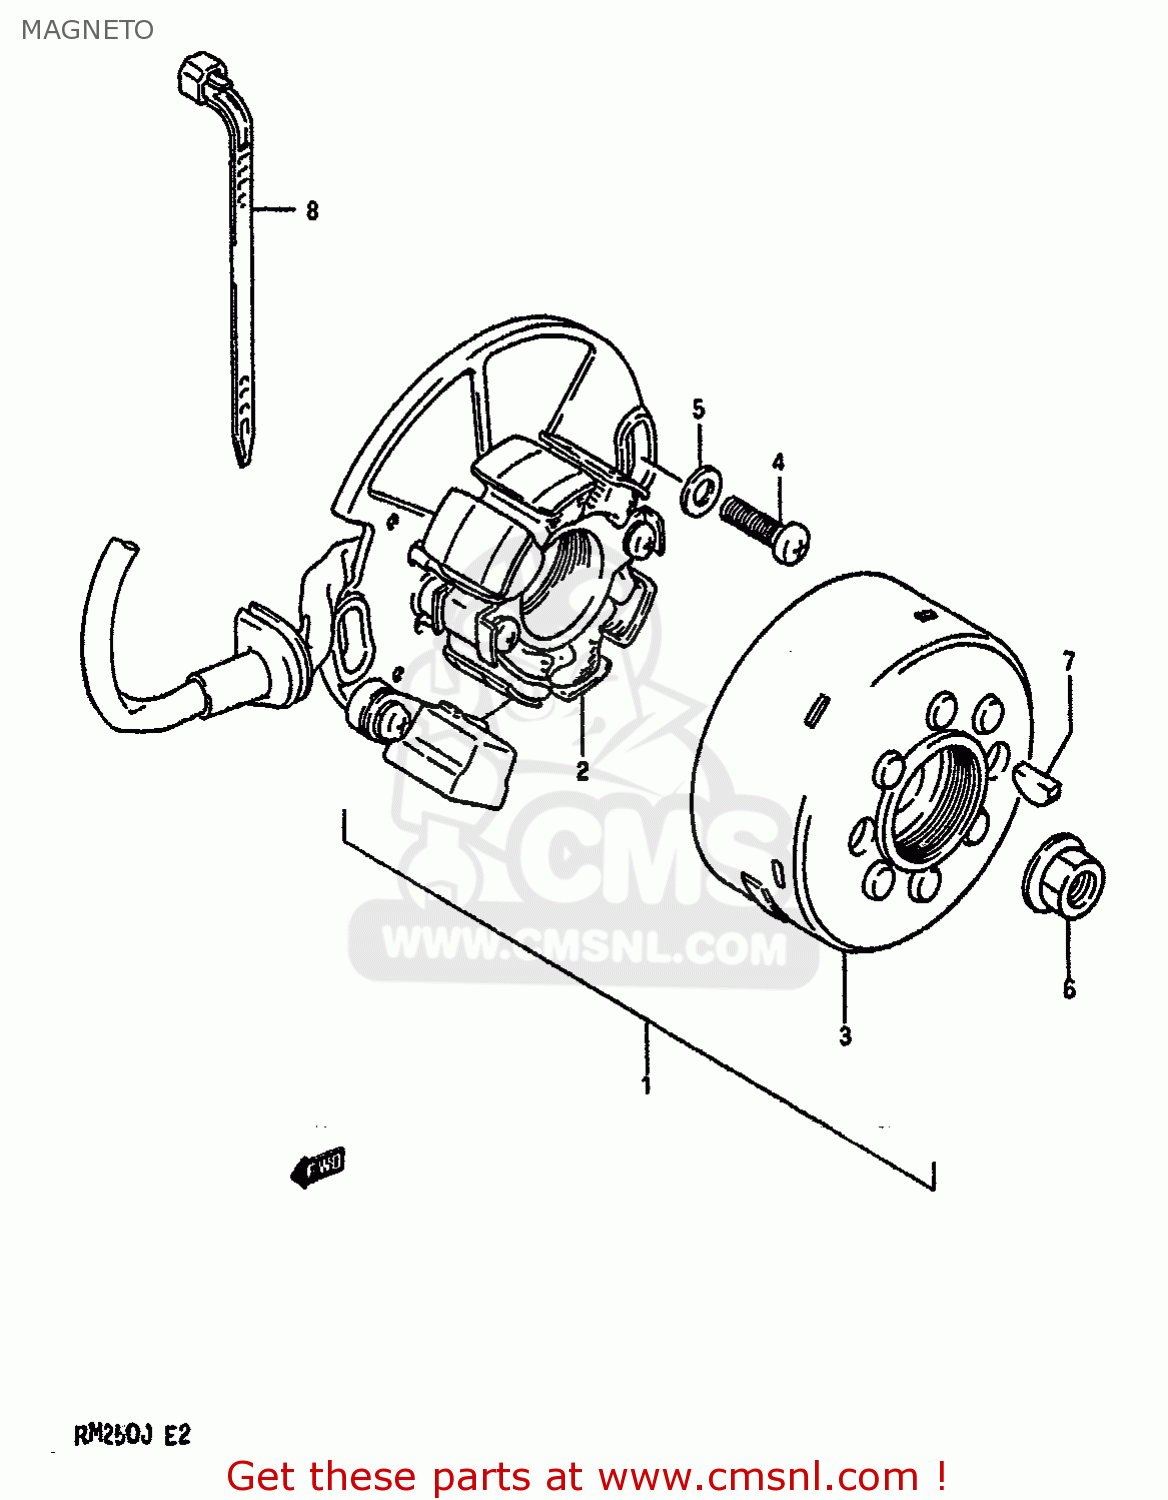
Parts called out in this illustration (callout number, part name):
1	MAGNETO ASSEMBLY
2	STATOR ASSEMBLY
3	ROTOR
4	SCREW
5	WASHER
6	NUT
7	KEY 4MM
8	CLAMP(L:125)
